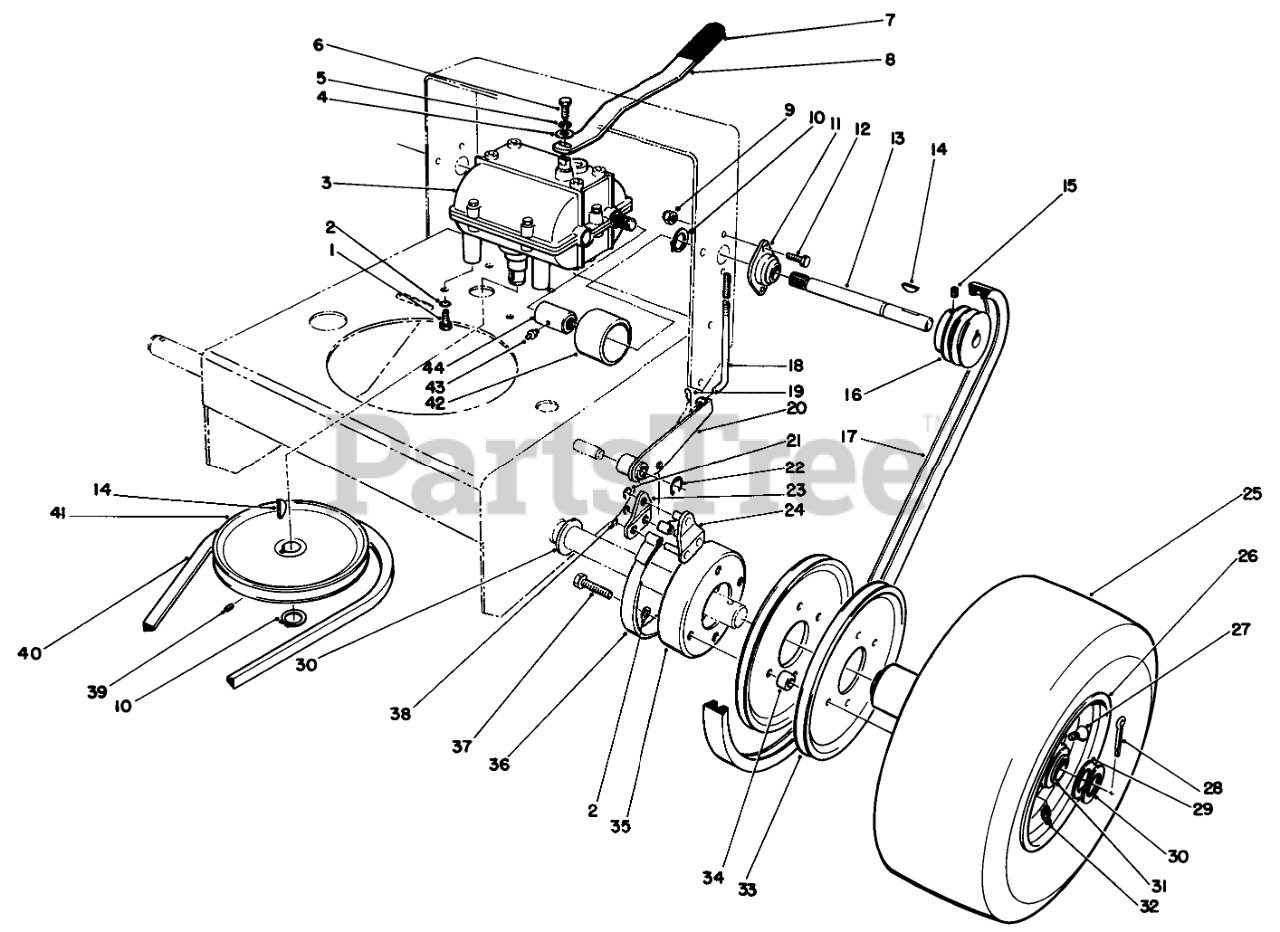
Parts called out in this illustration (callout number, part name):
1	SCREW-HH
2	WASHER-LOCK
3	Transmission
4	SPACER
5	WASHER-LOCK
6	SCREW-HH
8	LEVER-SHIFT
9	NUT-LOCK, NI
10	RING-SNAP, EXTERNAL
11	BEARING-EXTERNAL SHAFT
12	SCREW-HH
13	SHAFT-EXTENSION, RH
14	KEY-WOODRUFF
15	SCREW-SET, HSH
16	Pulley-Drive
17	V-BELT
18	ROD-BRAKE
19	PIN-COTTER
20	Brake Arm-LH
21	RING-RETAINING, EXTERNAL
22	RING-RETAINING
23	Plate-Link
24	LINK-BRAKE
26	WHEEL AND HUB ASM
27	STEM-VALVE
28	PIN-COTTER
29	WASHER-THRUST
30	WASHER-WHEEL
31	BEARING-BALL, FLANGED
32	FITTING-LUBE, 45 DEG
33	Pulley-Wheel
34	SPACER-PULLEY
35	Drum-Brake
36	BAND-BRAKE
37	SCREW-HH
38	RING-RETAINING
39	SCREW-SET
40	V-BELT
41	PULLEY-DRIVEN
42	GUARD-COUPLER
43	FITTING-GREASE
44	COUPLER
